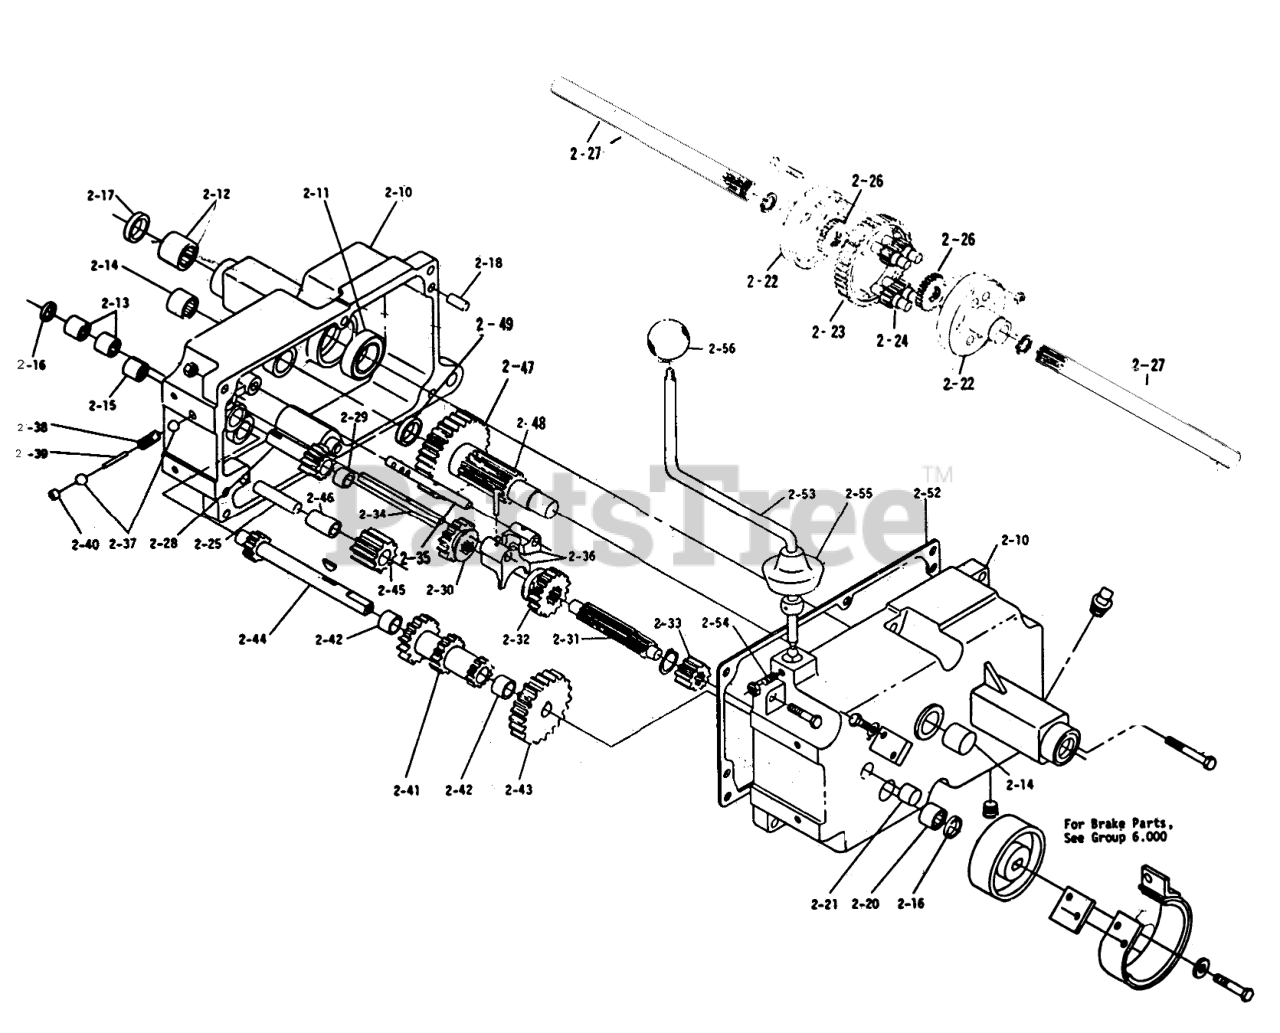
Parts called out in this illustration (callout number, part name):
2-10	Case R.H
2-11	BALL BRG 1 1/2 I.D.
2-12	BEARING-NEEDLE
2-13	NEEDLE BEARING
2-14	BEARING-NEEDLE
2-15	BEARING-NEEDLE
2-16	SEAL-OIL
2-17	OIL SEAL
2-18	Pin-Dowel
2-20	BEARING-NEEDLE
2-21	Bearing Needle
2-22	Case-Differential
2-23	Bull Gear
2-24	GEAR-PINION, 11T
2-25	PIN-DIFFERENTIAL
2-26	AXLE GEAR
2-27	Axle-Rear
2-28	INPUT SHAFT
2-29	BEARING-NEEDLE
2-30	GEAR
2-31	Shaft Spline
2-32	GEAR
2-33	GEAR
2-34	RAIL-SHIFT
2-35	RAIL-REAR SHIFT
2-36	FORK-SHIFT
2-37	BALL-DETENT
2-38	Spring
2-39	PIN-SHIFT
2-40	CUP-PLUG
2-41	Cluster Gear
2-42	BUSHING-BRONZE
2-43	GEAR-CLUSTER SHAFT
2-44	Cluster Shaft
2-45	GEAR/BUSHING ASM-REVERSE IDLER
2-46	BUSHING
2-48	PINION SHAFT
2-52	GASKET-TRANSMISSION
2-53	Shift Stick
2-54	SETSCREW
2-55	COVER-DUST
2-56	SHIFT KNOB
